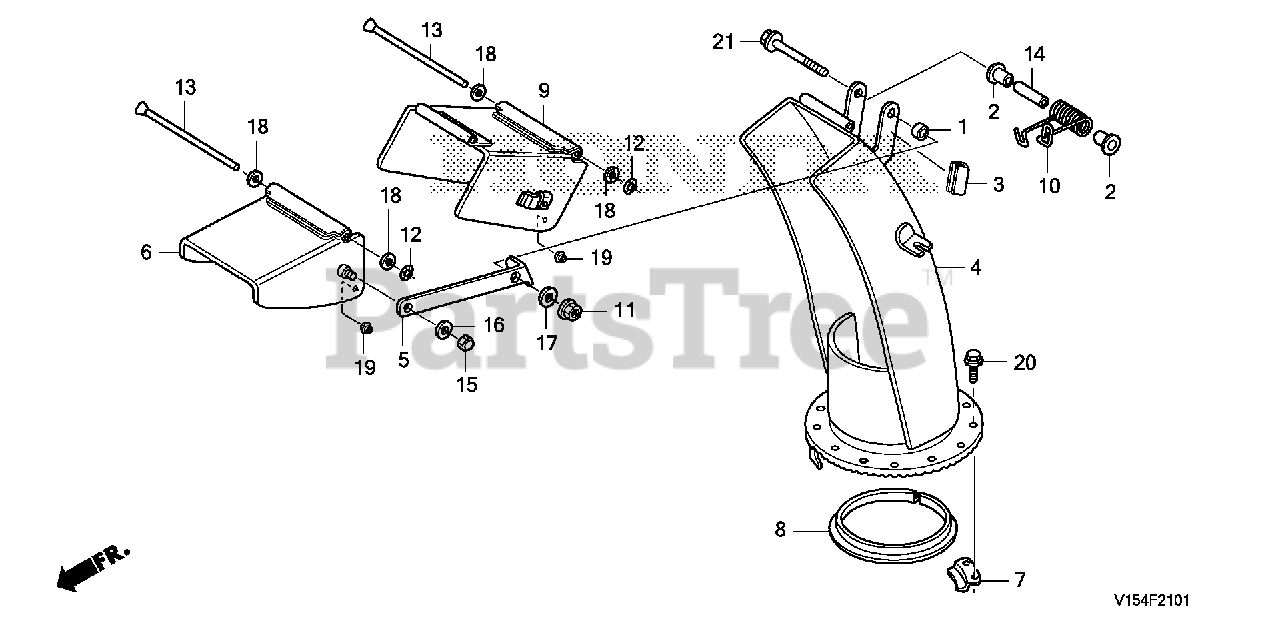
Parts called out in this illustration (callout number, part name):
1	COLLAR B, CHUTE LINK
2	BUSH, CYLINDER (UPPER)
5	PLATE, CHUTE LINK
6	GUIDE, CHUTE (COO)
7	PLATE, CHUTE SETTING
8	BUSH, CHUTE
9	GUIDE B, CHUTE
10	SPRING, CHUTE
11	NUT, FLANGE (8MM)
12	NUT, SPEED (6MM) (SOURCE: VINTAGE PARTS INC.)
13	PIN, CHUTE GUIDE
14	COLLAR, LINK CENTER
15	NUT, CAP (8MM)
16	WASHER, PLAIN (8MM)
17	WASHER, PLAIN (12MM) (SOURCE: VINTAGE PARTS INC.)
18	WASHER, PLAIN (6MM)
19	PLUG, BLIND (8MM)
20	BOLT, FLANGE (6X12)
21	BOLT, FLANGE (8X85)
